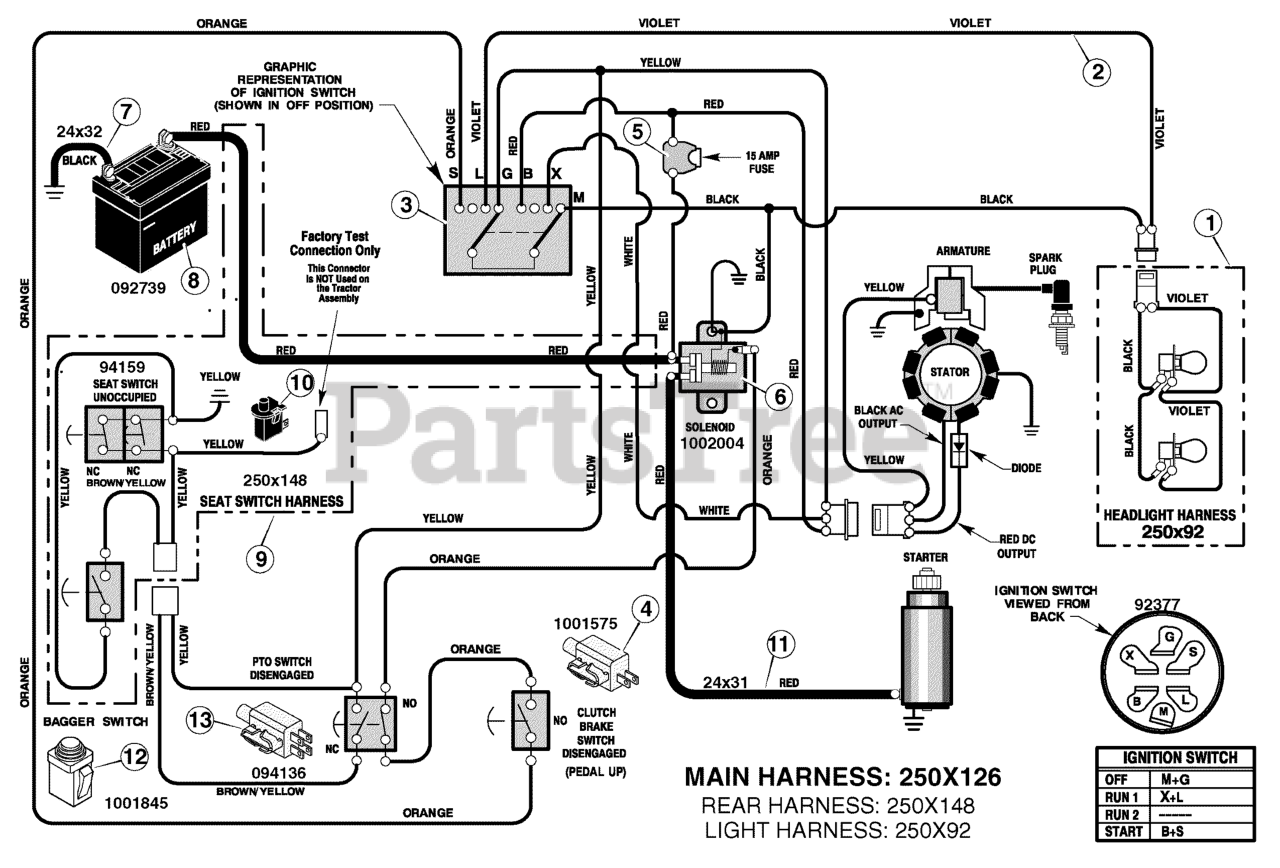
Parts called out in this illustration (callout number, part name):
1	Harness, Light Wire
1	Socket, Light
1	Bulb, Light
2	Harness, Chassis Wire
3	Switch, Ignition
3	Key, Ignition
3	Nut, Hex
3	Cap, Ignition
4	Switch, Limit
5	Holder, Fuse
6	Solenoid
6	Screw, Mounting
6	Locknut
7	Cable, Battery Ground
7	Screw, Ground Cable
8	Battery
8	Bolt, Carriage
8	Wingnut
8	BOOT, Battery Terminal, Positive
9	Harness, Seat Switch Wire
10	Switch, Seat Sensor
12	Switch, Bag Sensor
13	Switch, Limit
